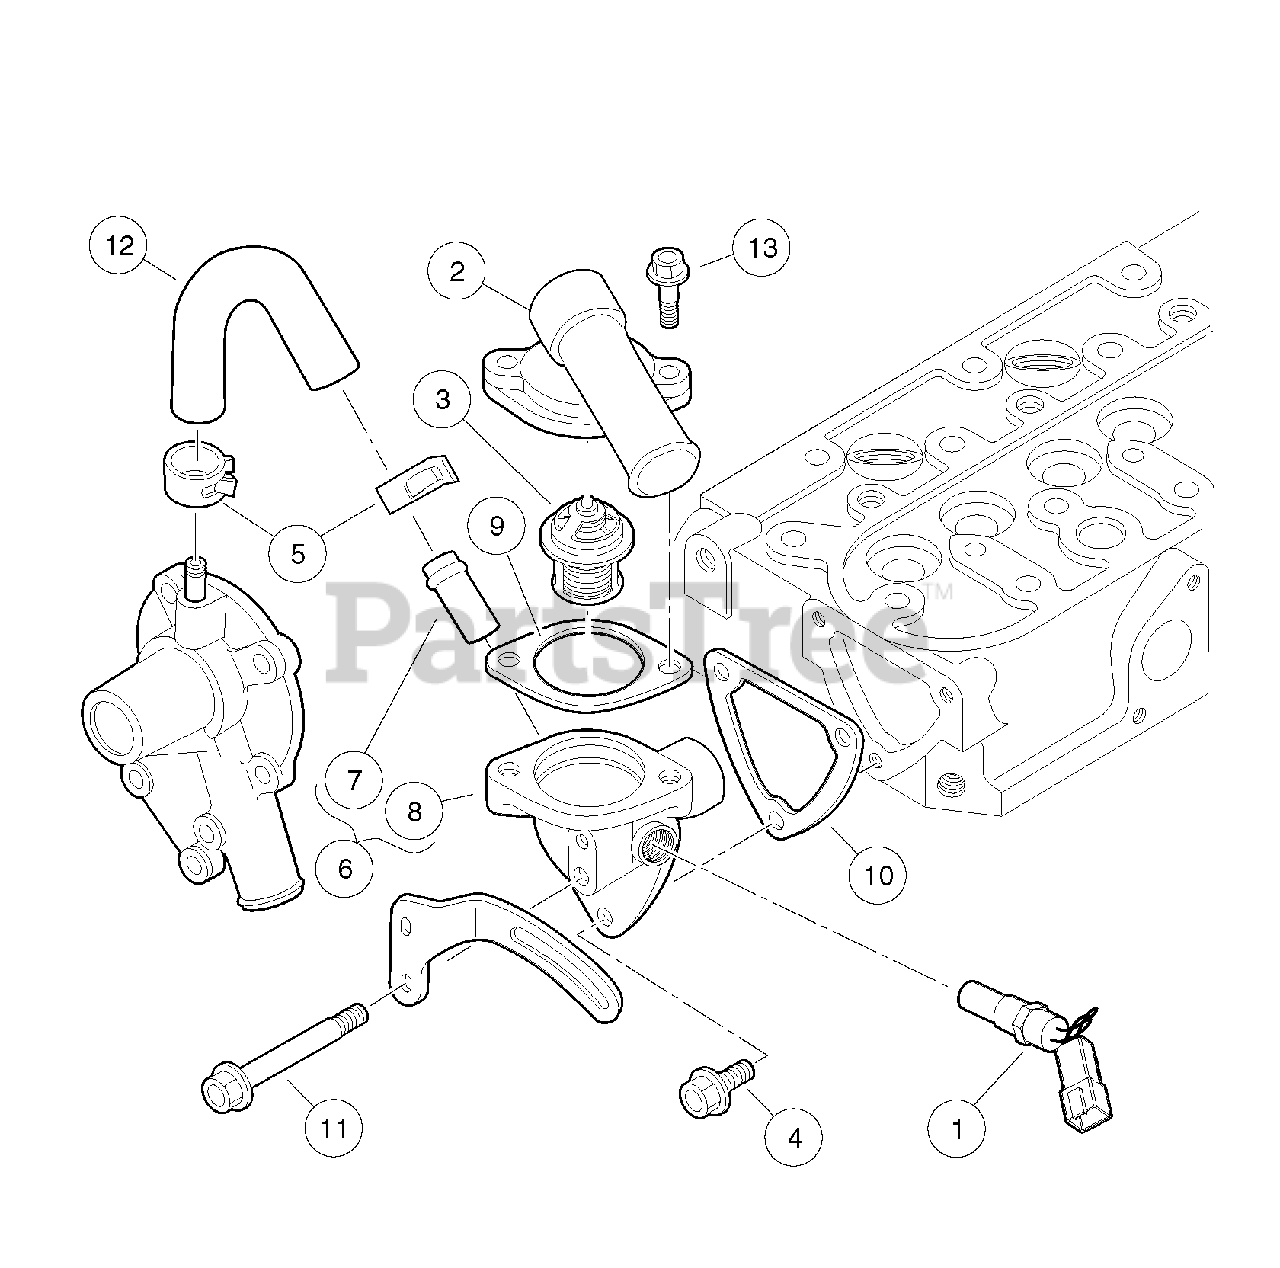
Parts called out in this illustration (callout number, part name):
1	Sensor, Coolant Temp
2	Cover, Thermostat
3	Assy, Thermostat
4	Bolt, M6 X 1 X 20
5	Band, Pipe
6	Flange, Water
7	Pipe, Water Return, D722
8	Flange, Water
9	Gasket, Thermostat
10	Gasket, Water Flange
11	Bolt, Alt, D722, Stay Lower
12	Pipe, Water Return, D722
13	Bolt, D722, Thermostat Cover
